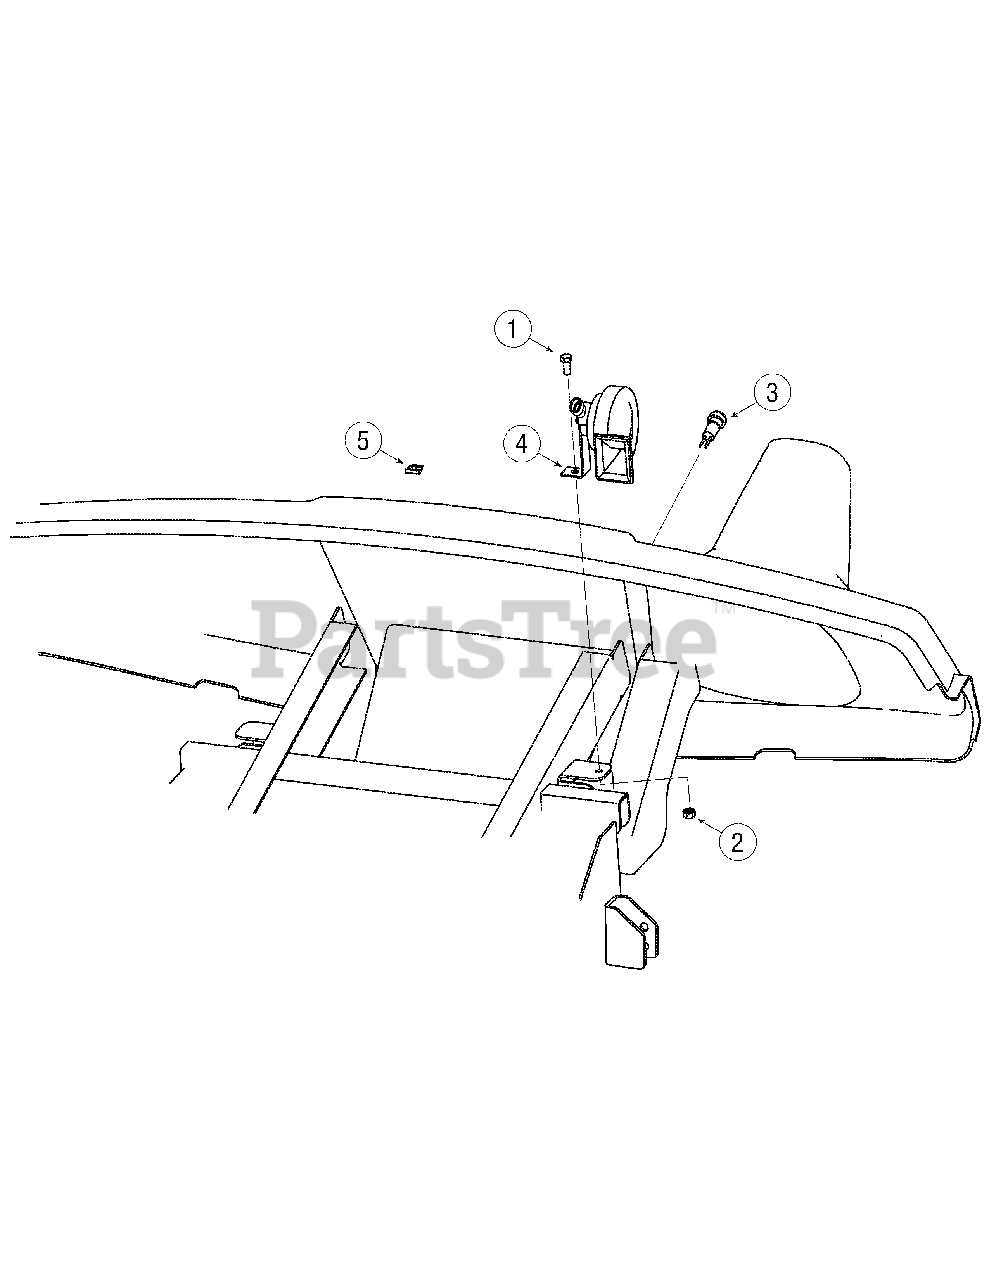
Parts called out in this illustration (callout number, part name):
1	SCREW 5/16-18 x .75 GR5
2	Nut, Sems, 5/16-18
3	Switch, Horn
5	Fuse, 7.5 amp
